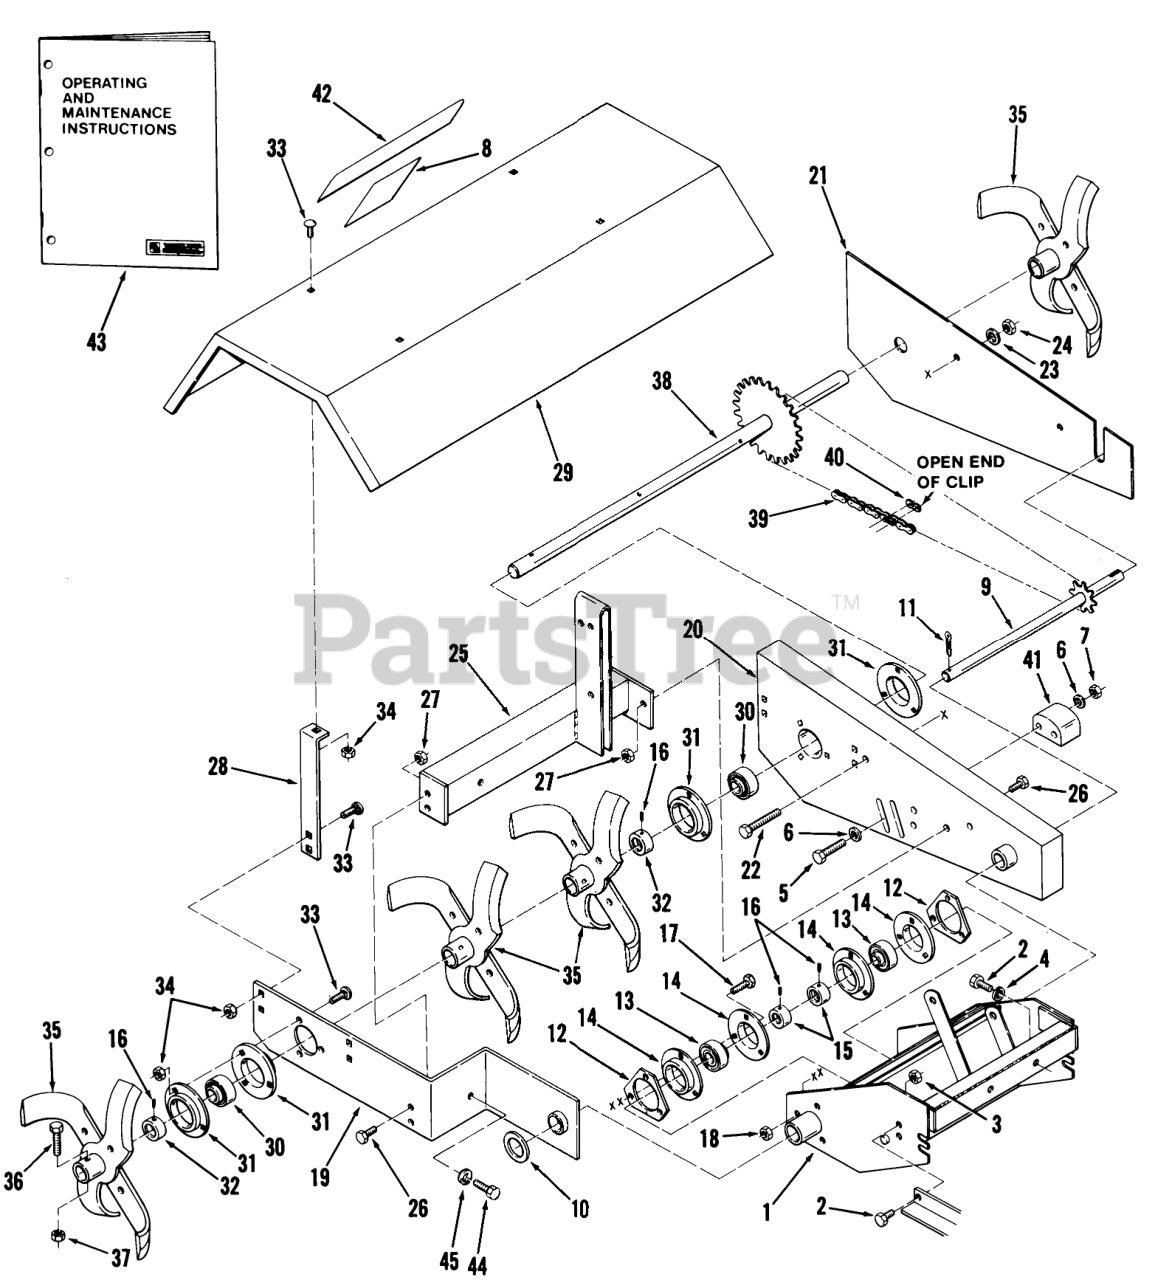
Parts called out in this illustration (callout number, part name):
6	WASHER 5/16 SAE
10	Washer 1 1/4 SAE
23	WASHER 5/16 SAE
42	DECAL-REAR
43	Operating and Maintenance Instructions 07-30TL01
43	Operating and Maintenance Instructions 07-30TL02
45	WASHER 5/16 SAE
